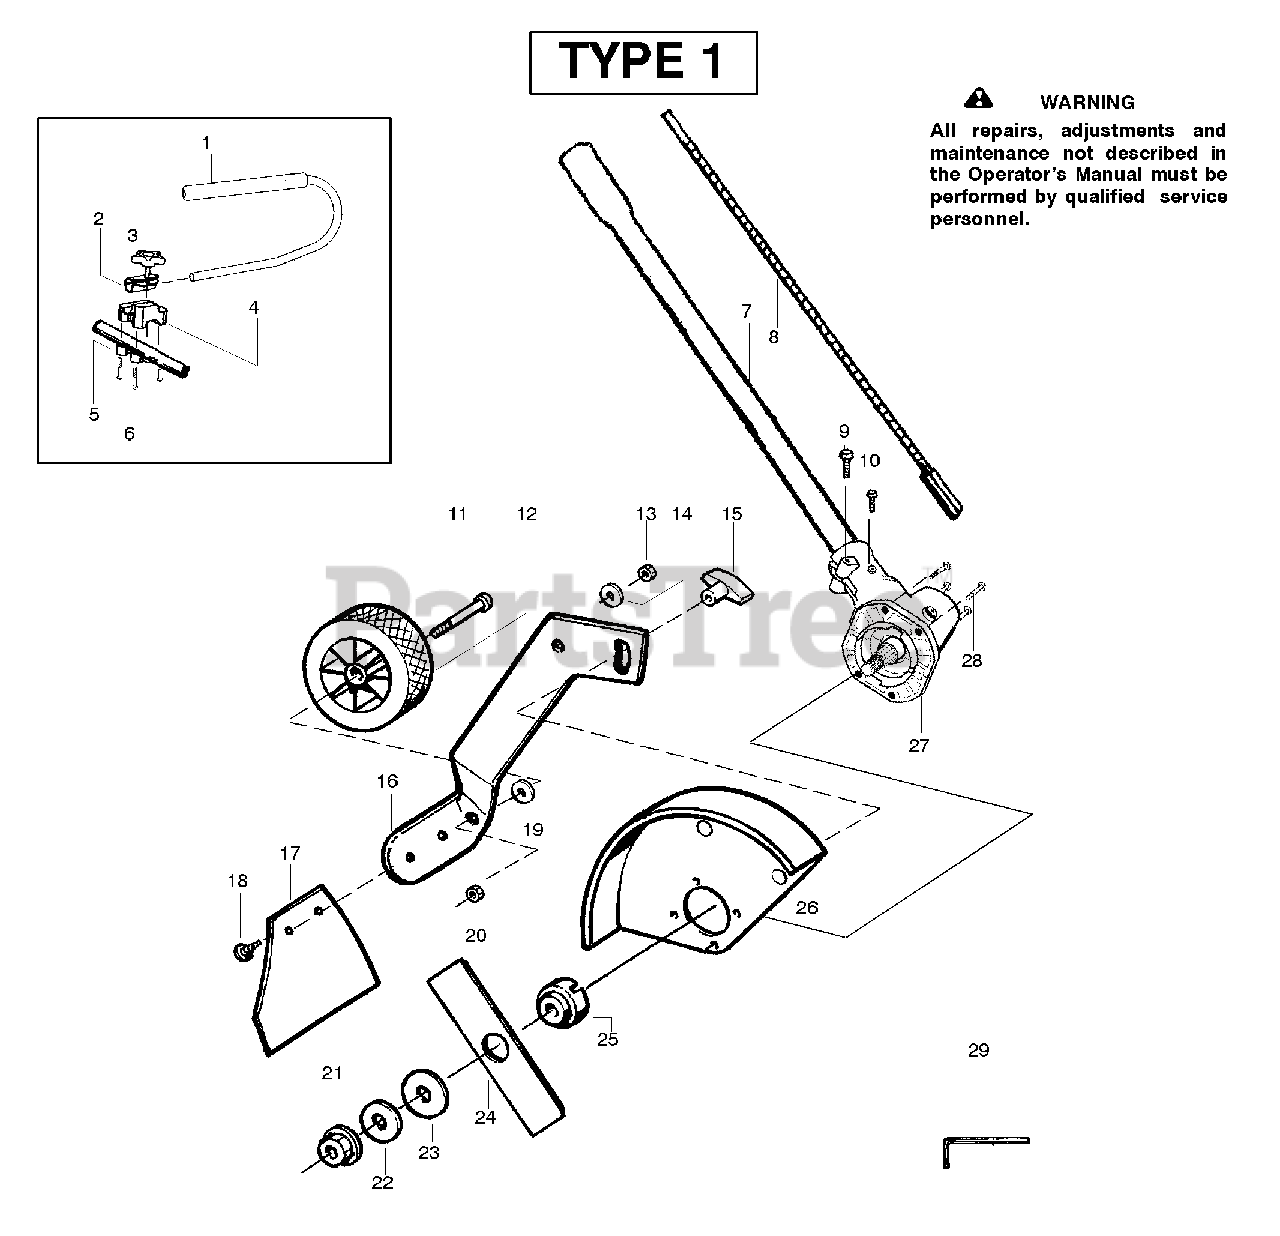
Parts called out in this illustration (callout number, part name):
1	Kit-Handlebar
2	Clamp
3	Knob
4	Base-Clamp
5	Kit-Tube Clamp
7	Assy.-Driveshaft
8	Flexshaft-Split boom
10	Screw-Alignment
11	Bolt-Shoulder Axle
12	Wheel-4"
16	Bracket-Adj. Wheel
17	Kit-Mud Flap
18	Fastener-Mud Flap
21	Nut-Flange
22	Washer-Belleville
23	Washer-Flat
24	Accy-7.5" Blade
26	Kit-Edger Guard
27	Kit-Gearbox
29	Wrench-Hex (5/32")
